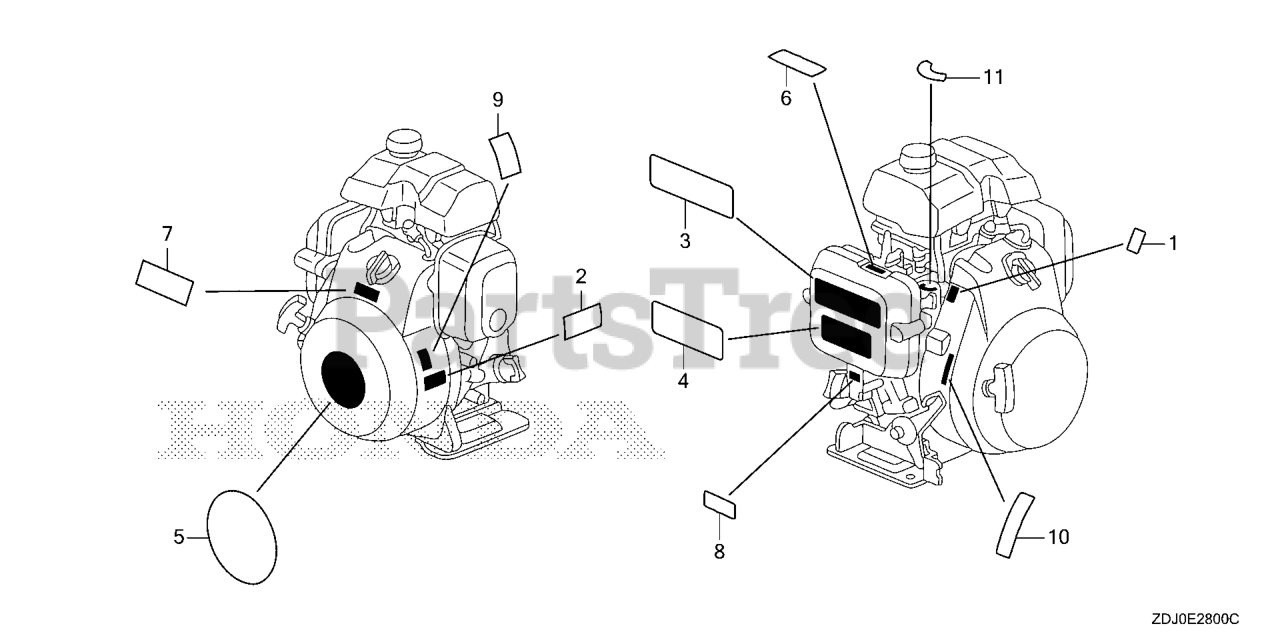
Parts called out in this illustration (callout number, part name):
3	MARK, OPER CAUTION
6	MARK, CHOKE INDICATION
8	MARK, TYPE (QXXB)
10	MARK, THROTTLE INDICATION
11	MARK, PETCOCK (EXTERNAL)
